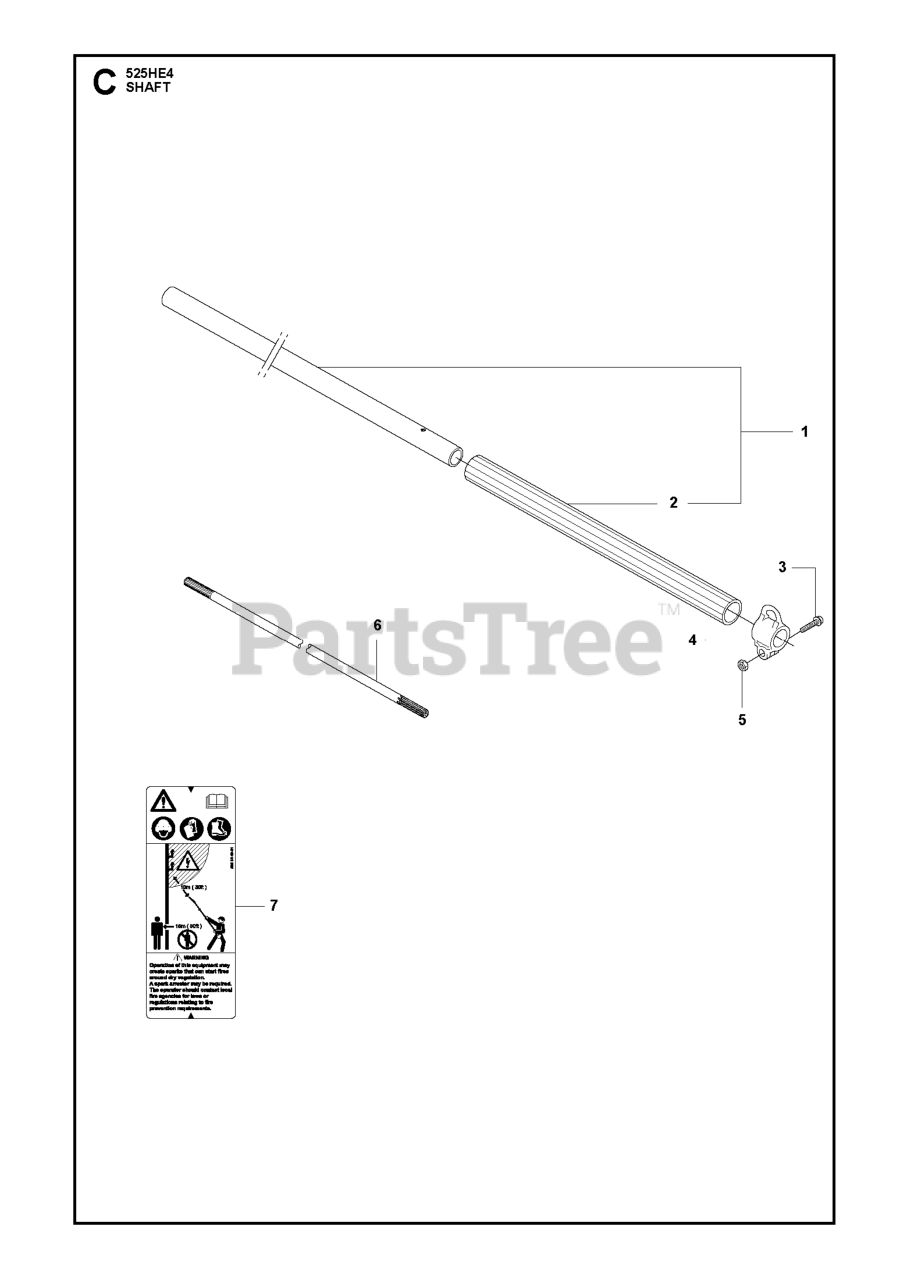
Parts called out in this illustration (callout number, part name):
4	HARNESS HOLDER
6	DRIVESHAFT
7	DECAL WARNING SPARK ARRESTOR
